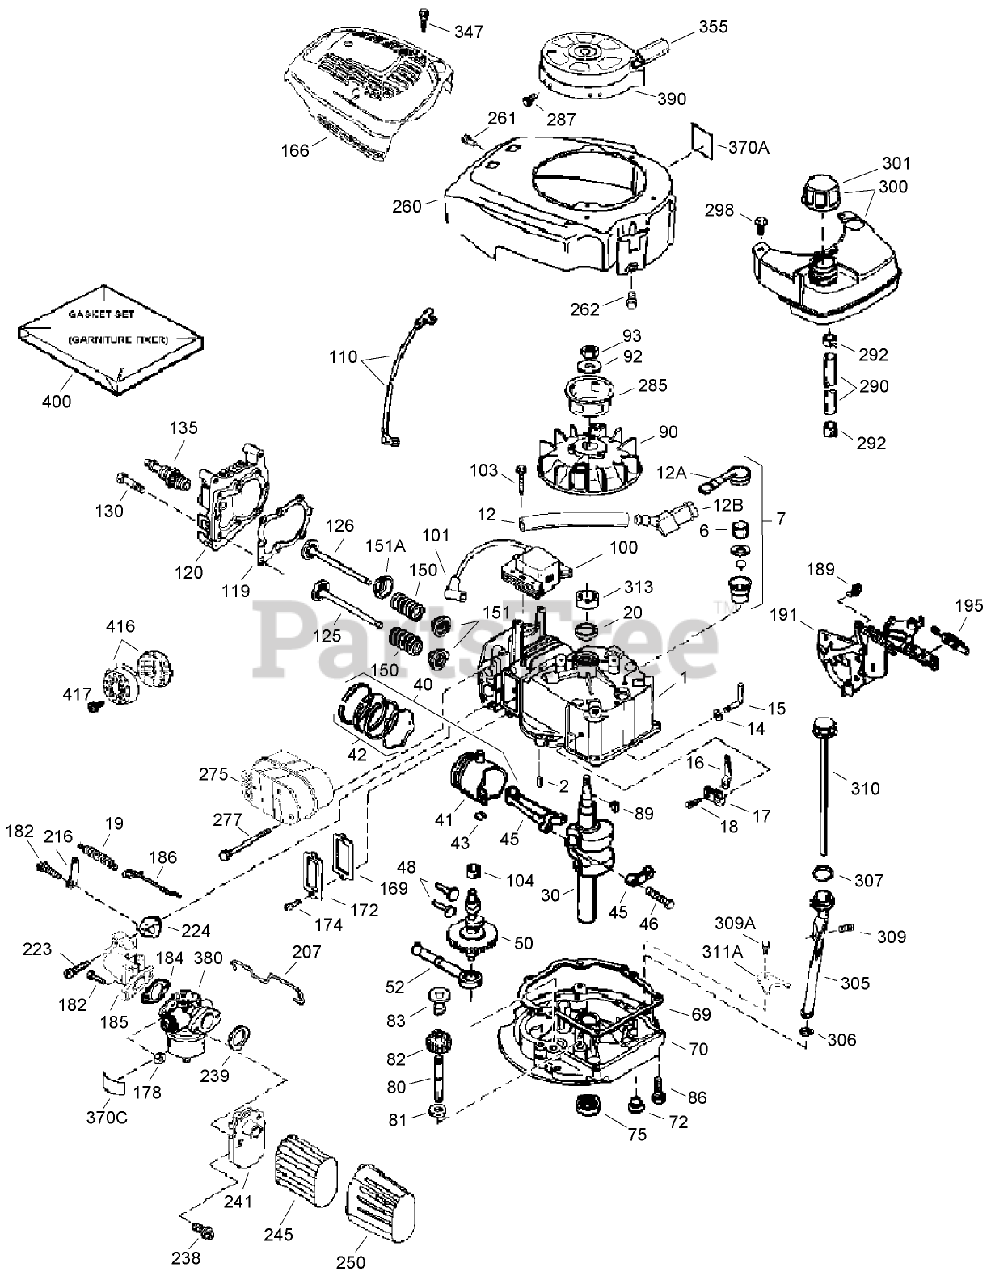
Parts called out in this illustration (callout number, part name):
347	Screw (10-32 x 27/32)
370	Decal-Warning
370A	Decal-Lubrication
370C	Decal-Primer
380	Carburetor (Incl. Ref. #184 of Engine Parts List)
390	Rewind Starter ASM
400	Gasket Set
416	Spark Arrestor Kit
